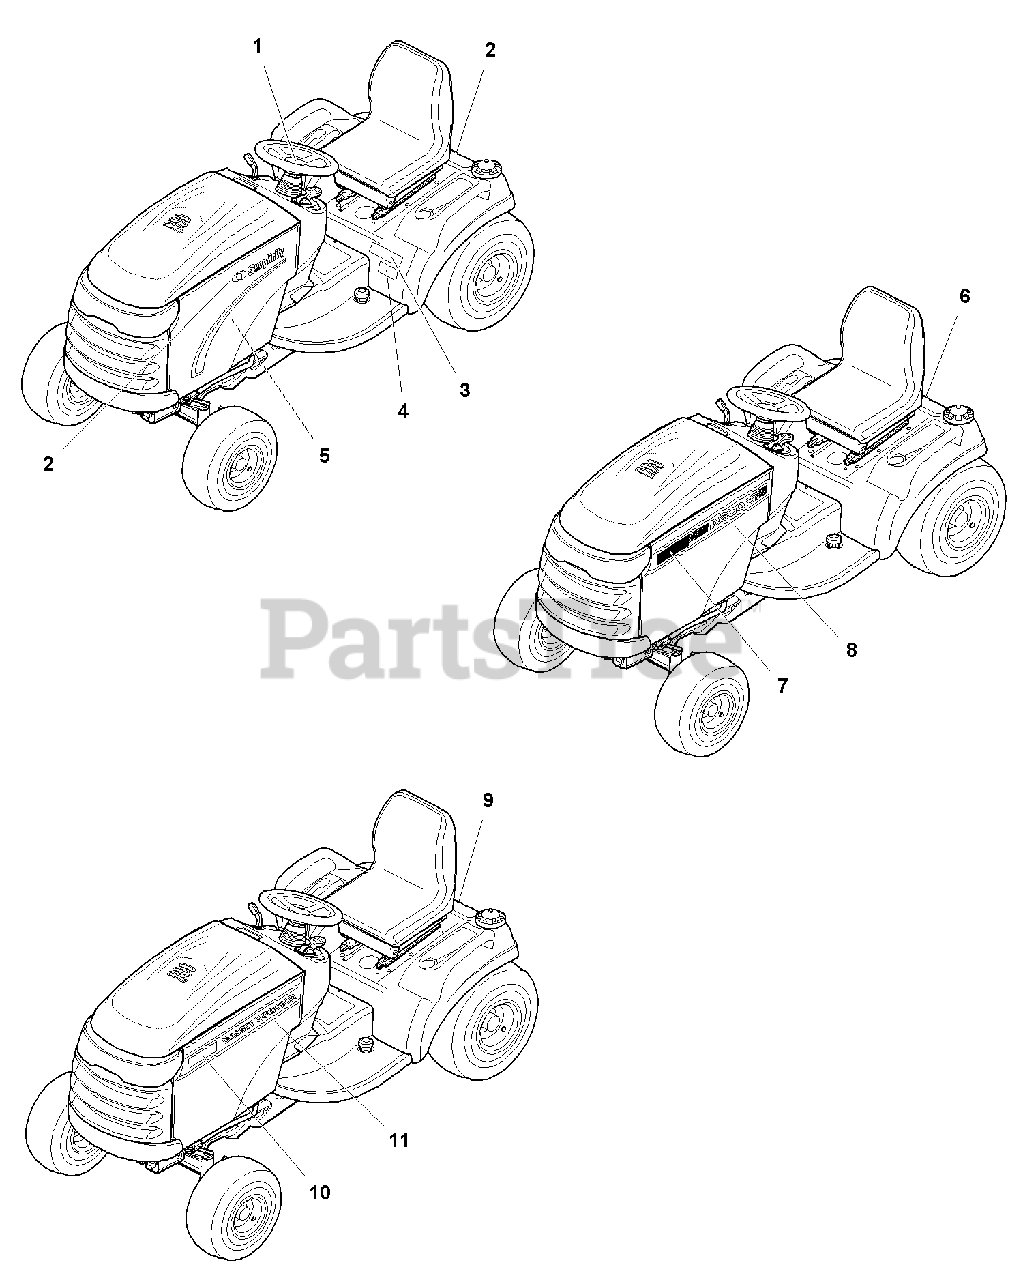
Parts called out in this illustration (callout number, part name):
1	DECAL, ICON Simplicity, 1 1/4 x 2 3/4, Orange
2	DECAL, Simplicity, Silver & Blue with Icon
3	DECAL, PRESTIGE, Silver & Blue
4	DECAL, 20HP, Silver
4	DECAL, 23HP, Silver
5	DECAL, Hood Stripe, RH, Simplicity, Blue & Silver
5	DECAL, Hood Stripe, LH, Simplicity, Blue & Silver
6	DECAL, AGCO, Logo Black, Chrome, Orange
7	DECAL, 1820 White, AGCO
7	DECAL, 1823, White, AGCO
8	DECAL, Hood Stripe, LH, AGCO
8	DECAL, Hood Stripe, RH, AGCO
9	DECAL, Massey Ferguson Logo, 3 Triangles
10	DECAL, 2820, Black, Massey Ferguson
10	DECAL, 2823, Black, Massey Ferguson
11	DECAL, Hood Stripe, LH, Massey Ferguson
11	DECAL, Hood Stripe, RH, Massey Ferguson
